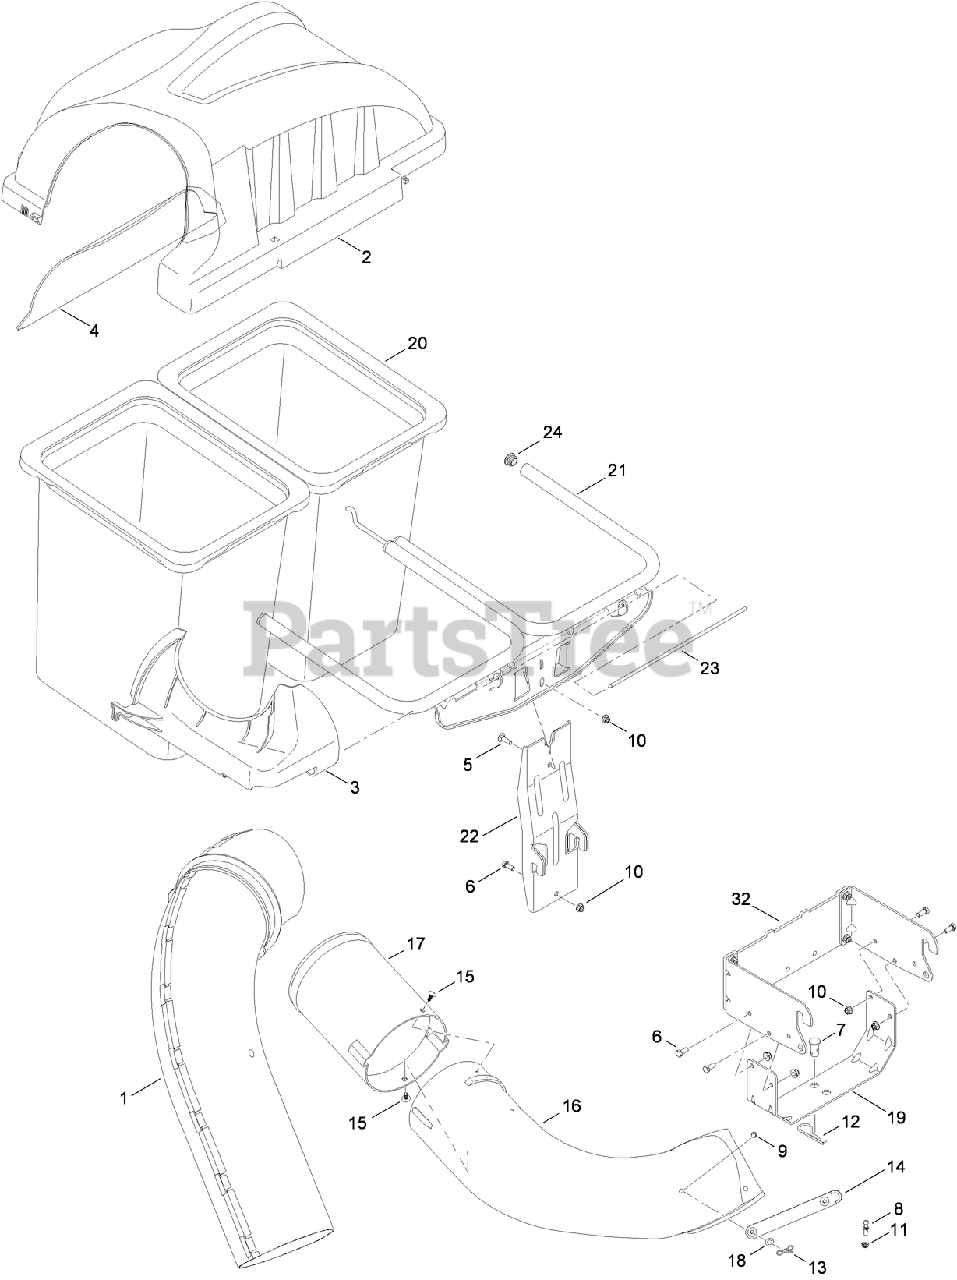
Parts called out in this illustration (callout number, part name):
1	UPPER CHUTE ASM
2	DOUBLE BAGGER COVER ASM
3	SUPPORT-CHUTE, UPPER
4	SCREEN-COVER, BAGGER
5	BOLT-CARR
6	SCREW-HH
7	PIN-CLEVIS
8	PIN-CATCHER, GRASS
9	PIN-CLEVIS
10	NUT-LOCK, FLANGE
11	NUT-LOCK, FLANGE
12	CLIP-HAIRPIN
13	PIN-COTTER
14	STRAP-CHUTE
15	CLIP-RATCHET, FASTENER
16	ELBOW-CHUTE, DISCHARGE
17	ADAPTER-CHUTE, DISCHARGE
18	WASHER-FLAT
19	SUPPORT-BRACKET, UNIVERSAL
20	GRASS BAG ASM
21	DOUBLE BAG SUPPORT ASM
22	BRACKET-SUPPORT, VERTICAL
23	PIN-HINGE, COVER
24	PLUG-END
32	HITCH BRACKET ASM
